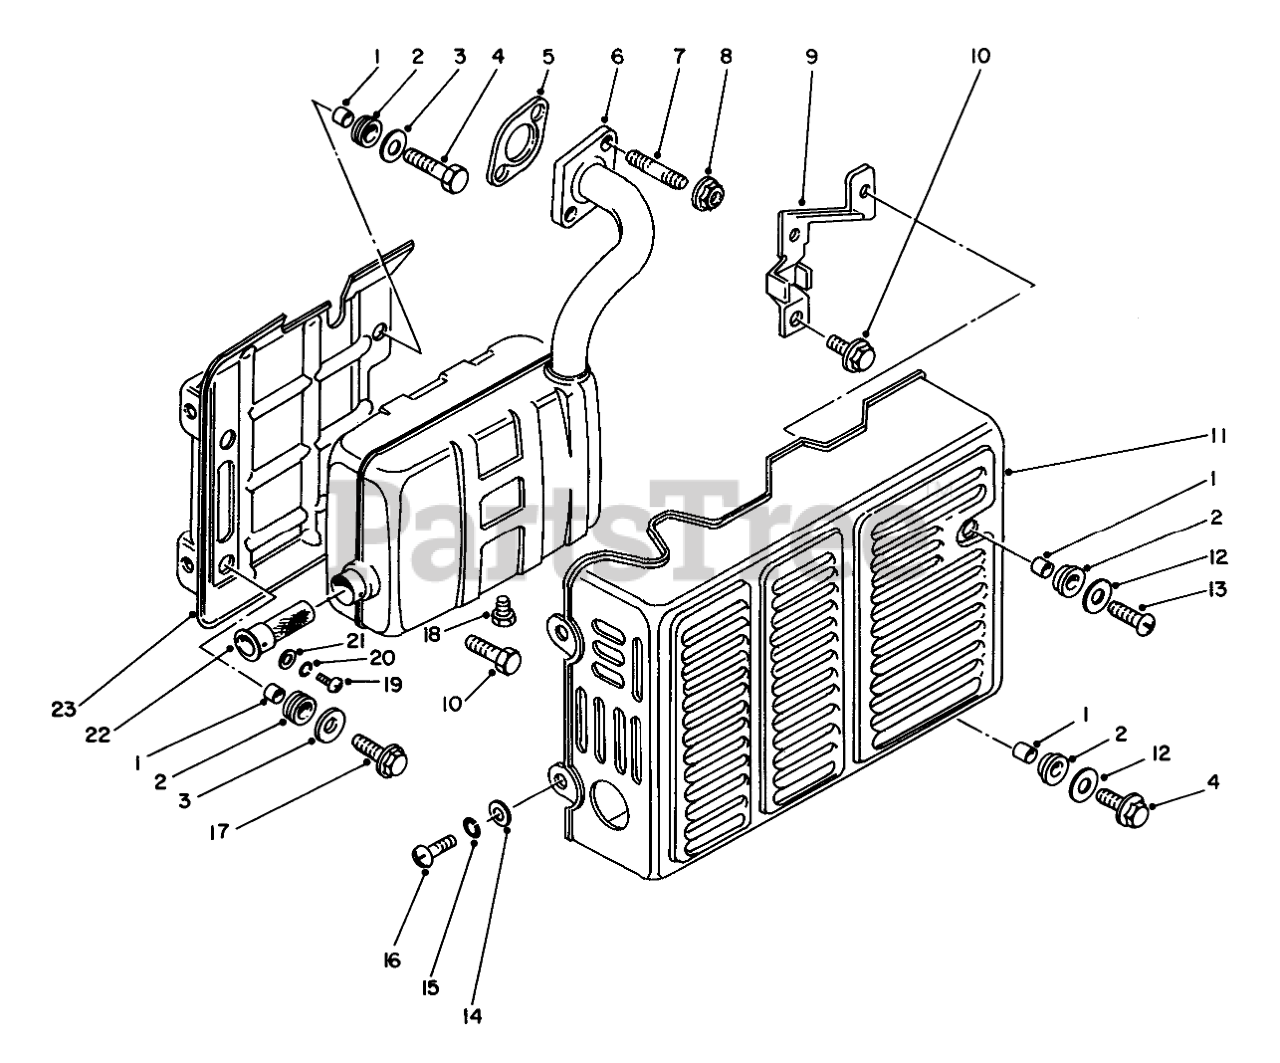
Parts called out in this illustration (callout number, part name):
1	Spacer
2	Cushion
3	Washer
5	Gasket
6	Muffler
7	Bolt-Stud
9	Bracket-Governor Spring
11	COVER
12	Washer
13	Screw
14	Washer
15	Washer-Lock
16	SCREW
18	Plug-Drain
20	Lockwasher
21	Washer
22	Spark Arrestor
23	Cover-Rear
